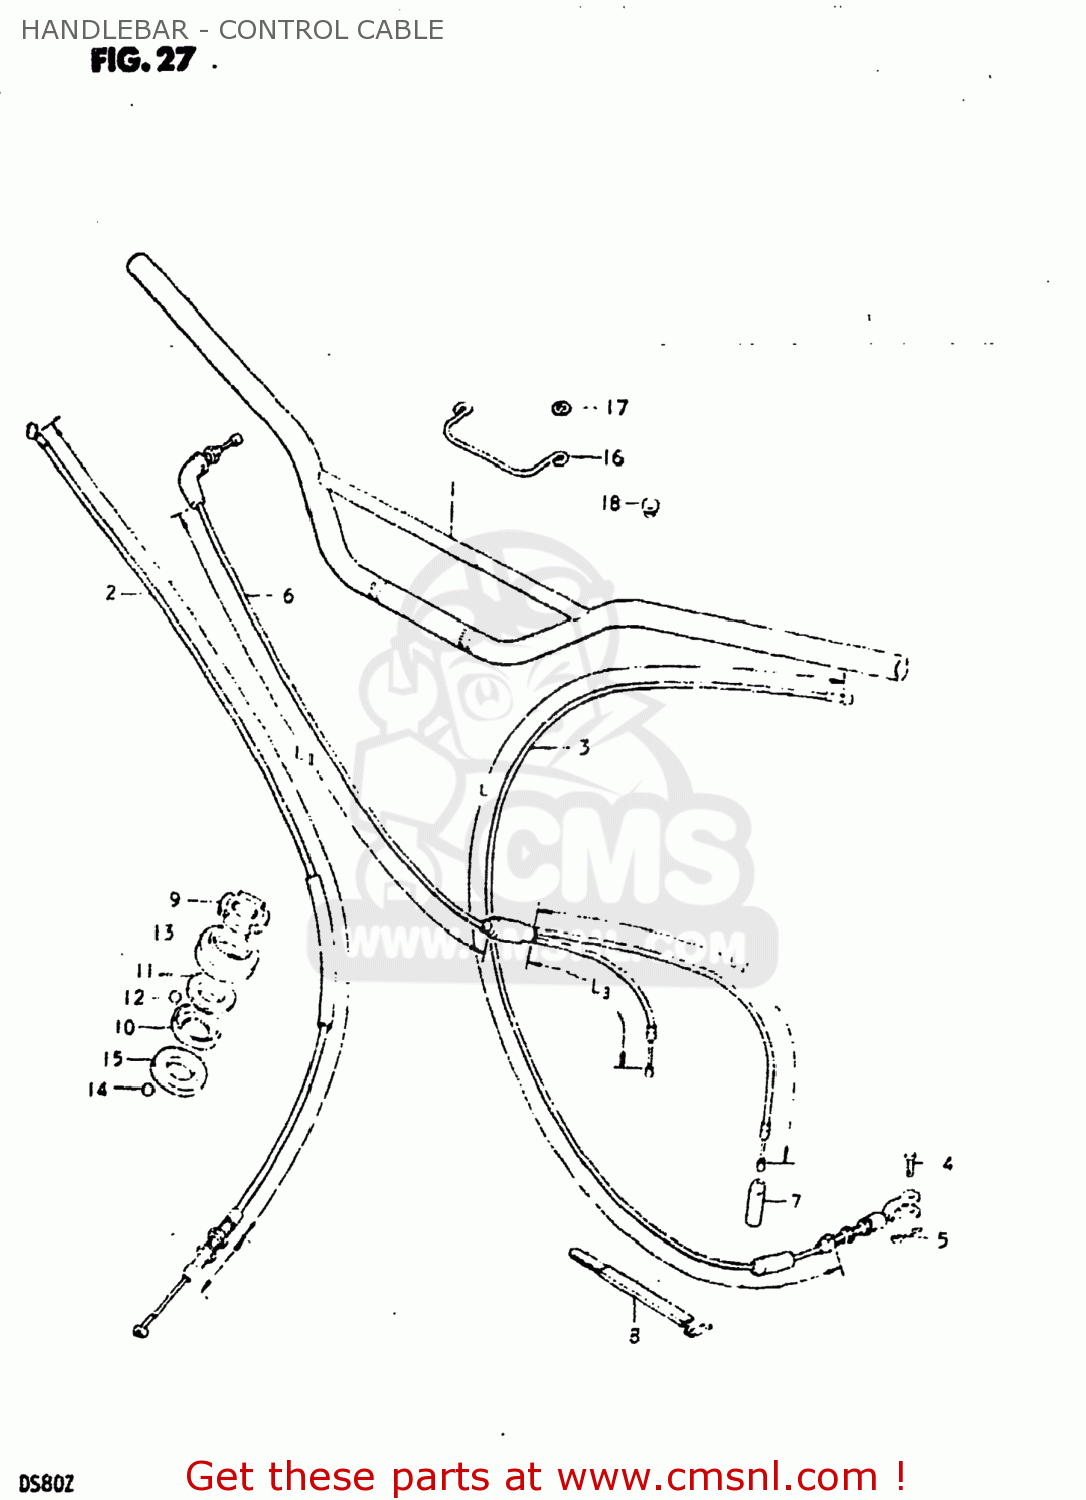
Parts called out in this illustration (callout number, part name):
1	HANDLEBAR
2	CABLE ASSEMBLY,FRONT BRAKE
3	CABLE,CLUTCH
4	PIN(L:13)
5	PIN
6	CABLE ASSEMBLY,THROTTLE
7	SEAL,DUST(7X18X30)
8	CLAMP
9	NUT,STEERING STEM(25X44X10)
10	RACE,STEERING INNER UPR
11	RACE,STEERING OUTER UPR
12	BALL
13	DUST SEAL,STEERING UPR
14	BALL
15	LACE,STEERING INNER LWR
16	GUIDE,CABLE
17	WASHER
18	CAP
